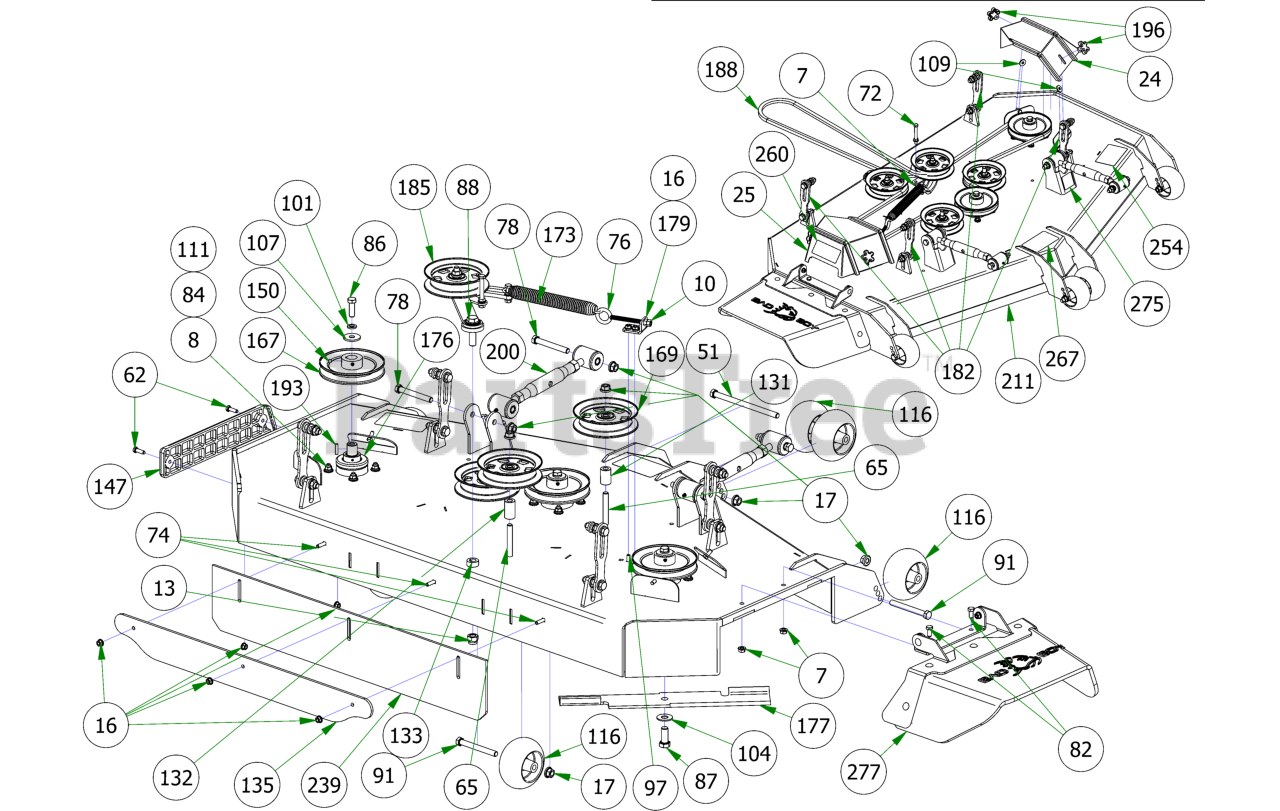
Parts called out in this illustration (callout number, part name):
7	3/8-16 HEX SERRATED FLANGE NUT HARD/ZINC
8	3/8-16 NYLON INSERT FLANGE LOCKNUT (GR.F) ZINC
10	3/8-16 HEX NUT ZINC
13	5/8-11 NYLON INSERT LOCKNUT ZINC
16	5/16-18 NYLON INSERT FLANGE LOCKNUT ZINC
17	1/2-13 NYLON INSERT FLANGE LOCKNUT ZINC
24	2019 61" Outlaw Gen2 Pulley Cover Left
25	2019 61" Outlaw Gen2 Pulley Cover Right
51	1/2-13 X 8 HEX CAP SCREW GR 5 ZINC
62	5/16-18 X 1 HEX CAP SCREW (GR.5) ZINC
65	1/2-13 X 3-1/2 HEX FLANGE BOLT (GR.8) ZINC
72	3/8-16 X 3 HEX CAP SCREW (GR.5) ZINC
74	5/16-18 X 1-1/4 CARRIAGE BOLT ZINC
76	4" 3/8-16 Eye Bolt
78	1/2-13 X 4 HEX CAP SCREW (GR.8) ZINC YELLOW
82	3/8-16 X 3/4 HEX CAP SCREW (GR.5) ZINC
84	3/8-16 X 1-1/2 HEX CAP SCREW (GR.5) ZINC
86	1/2-20 X 1-1/2 HEX CAP SCREW (GR.5) ZINC
87	5/8-18 X 1-1/2 HEX CAP SCREW (GR.8) ZINC YELLOW
88	5/8-11 X 2-1/2 HEX CAP SCREW (GR.5) ZINC
91	1/2-13 X 4-1/2 HEX CAP SCREW (GR.5) ZINC
97	5/16-18 X 7/8 CARRIAGE BOLT ZINC
101	1/2 SPLIT LOCKWASHER (GR.8) ZINC/YELLOW
104	5/8 USS FLAT WASHER (1-3/4" OD) GR.8 ZINC YELLOW
107	1/2 BELLEVILLE WASHER (1-5/8 OD X .140 THK) ZINC
109	.360 ID X .983 OD X .120 THICK FLAT WASHER NYLON BLACK
111	5/16 USS FLAT WASHER (7/8 OD) ZINC
116	2019 Deck Wheel
131	.502 ID X .750 OD X 1.500 Long Spacer
132	1 3/4" Pulley Spacer
133	5/8 SOLID SHAFT COLLAR (W/1 SET SCREW) ZINC
135	61 Bolt in Baffle Deck v2 Stripping Plate
147	REVISED TRIM BUMPER_20180226
150	5/16-24 X 1/4 SOCKET SET SCREW (CUP PT) PLAIN
167	6 1/4" Drive Pulley
169	5-3/4 Idler Pulley
173	2019 Outlaw Gen2 Deck Spring
176	OUTLAW SPINDLE ASSEMBLY
177	61 inch Fusion Blade
179	2019 Deck Eye Bolt Tab
182	Deck Hanger Assembly
185	2019 Renegade Deck Idler
188	Deck Belt for 61" Renegade
193	1/4 X 1 SQ MACHINERY KEY 1018 STL PLN
196	5/16" Knob
200	Turnbuckle
211	2019 Sloped 61" Deck
239	R Series Rubber For Deck
254	2018 61" Deck Decal
260	Danger Decal-Spindle/Discharge
267	2019 Renegade Deck Belt Route Decal
275	Deck Impact Patent Decal 9591803
277	2019 Outlaw Gen2 Chute Assembly
